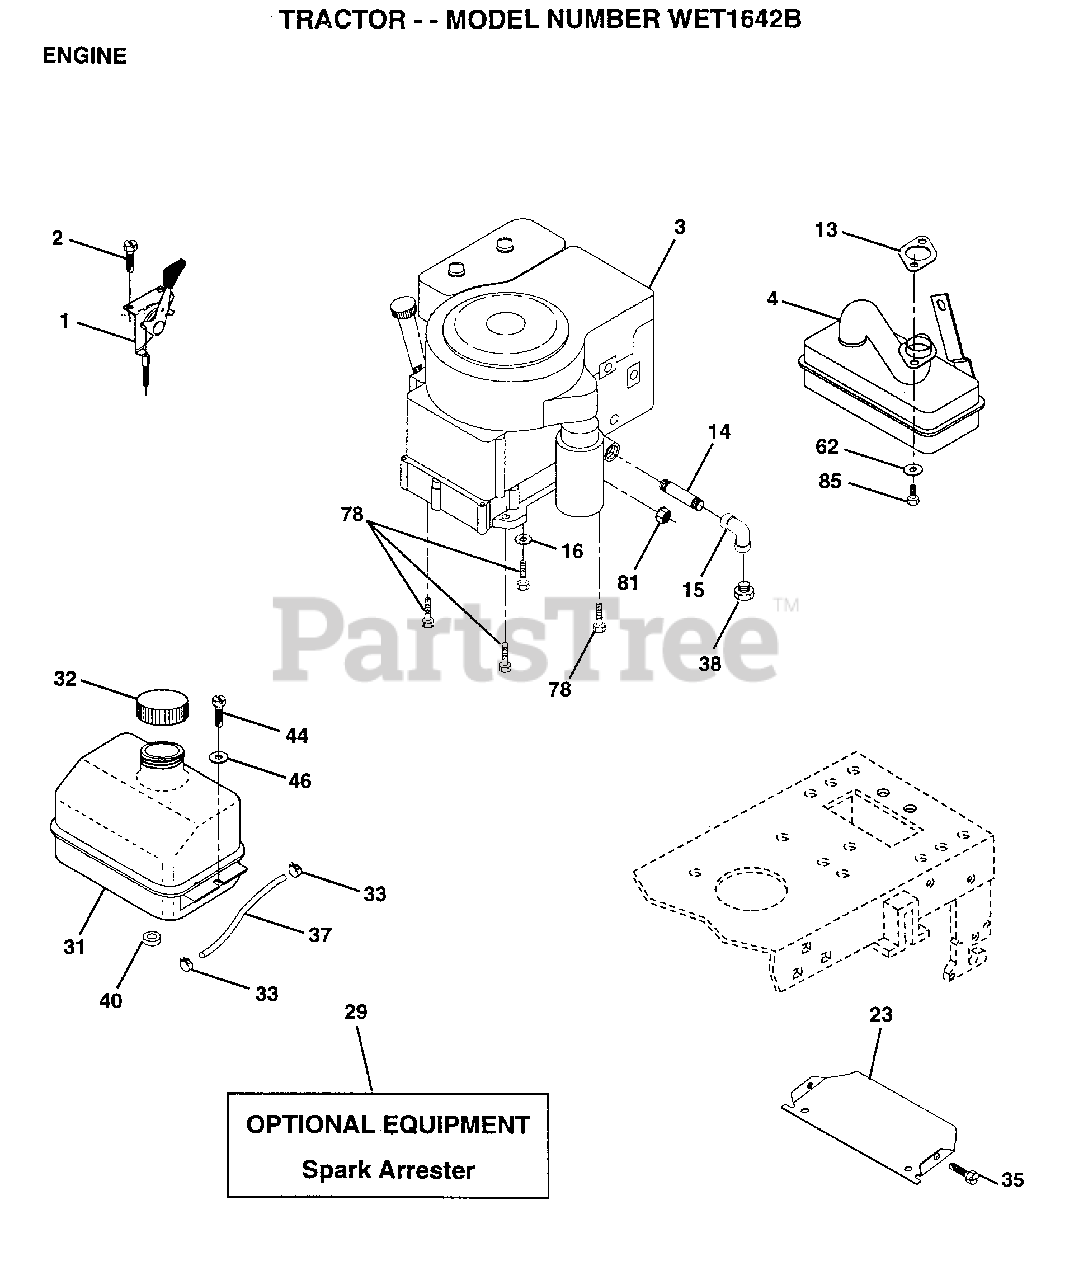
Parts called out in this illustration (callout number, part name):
1	THROTTLE CONTROL
2	SCREW LT
3	ENGINE, TEC 16HP
4	MUFFLER
13	GASKET MUFFLE TEC
14	PIPE NIPPLE LT
15	ELBOW
16	LOCKWASHER
31	TANK.FUEL.LT.
32	CAP ASM FUEL
33	HOSE CLAMP
35	SCREW
37	LINE FUEL
44	SCREW HEX CRT
46	WASHER
62	LOCKWASHER
78	SCREW
81	NUT
85	SCREW HEX HD CAP
